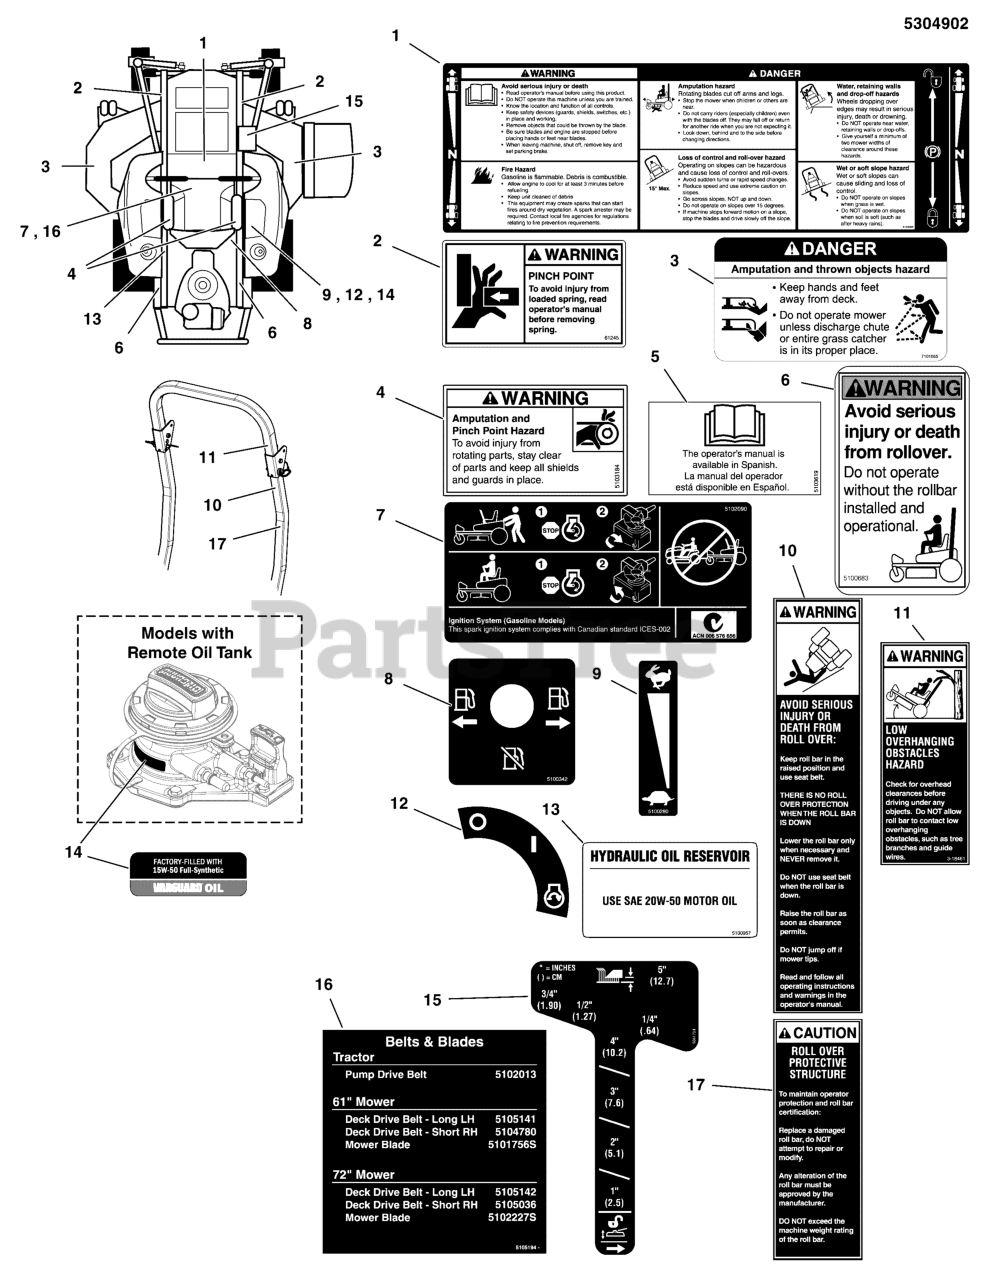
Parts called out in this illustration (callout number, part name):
1	DECAL, MAIN SAFETY
2	DECAL, PINCH POINT
3	DECAL, DANGER DO NOT OPERATE W/O DEFLECT
4	DECAL, WARNING, HAND IN BELT, ENG ONLY
5	DECAL, MANUAL AVAIL IN SPANISH
6	DECAL, WARNING, ROLL BAR
7	DECAL, TRANSAXLE RELEASE, S200XT
8	DECAL, FUEL VALVE
9	DECAL, THROTTLE CONTROL
10	DECAL, WARNING, FOLDING ROPS
11	DECAL, WARNING & CAUTION, ROPS
12	DECAL, IGNITION SWITCH
13	DECAL, HYDRAULIC OIL, SAE 20W50
14	LABEL, OIL INFORMATION
15	DECAL-HEIGHT CITATION
16	DECAL, BELT & BLADE, F320Z, 2BELT
17	DECAL, CAUTION. FOLDING ROPS
